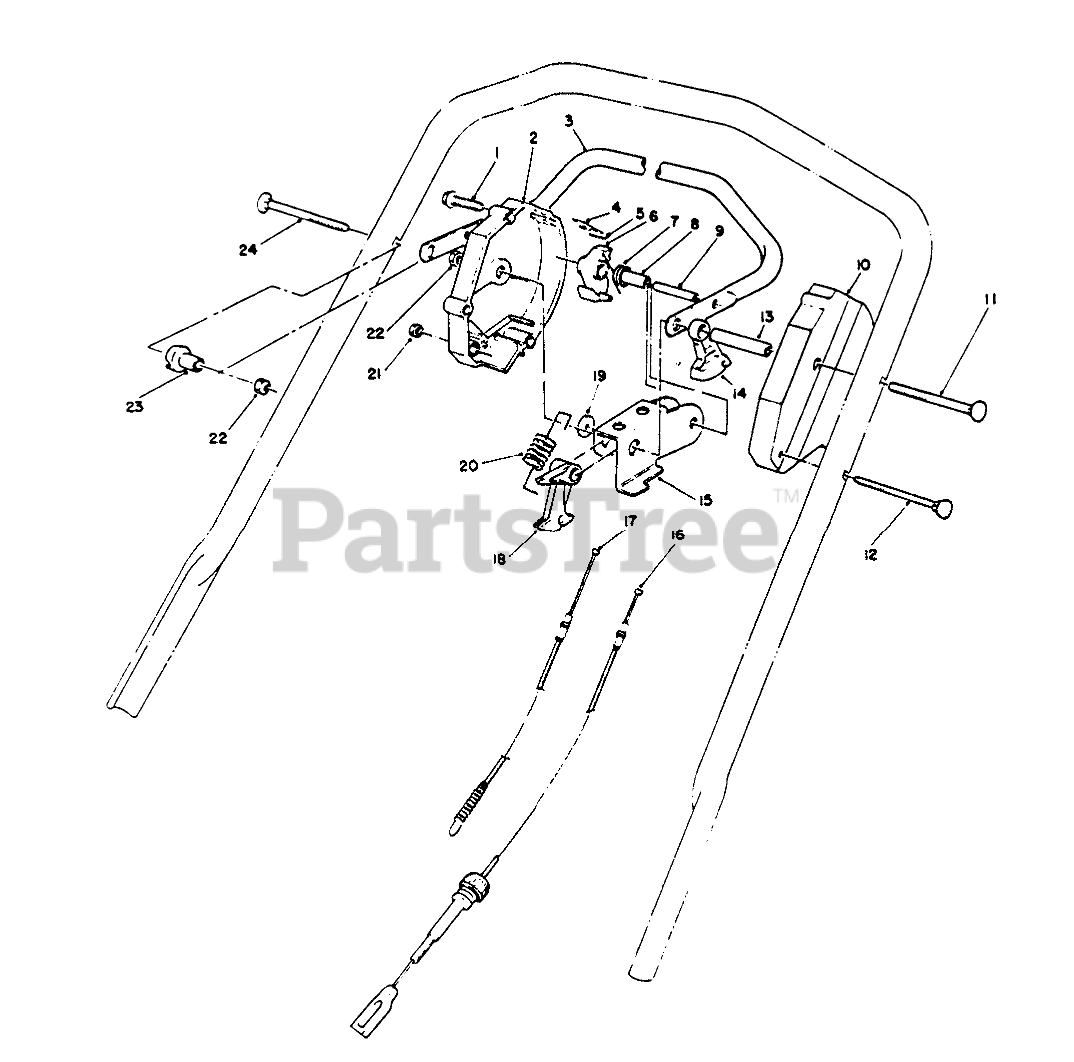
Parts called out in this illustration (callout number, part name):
1	SCREW-HWHTF
2	Housing-Control R.H. (Incl Ref. #4 & 5)
3	Bar-Control
4	SPRING-LEAF
5	PIN-INSERT
6	HOOK-CONTROL
7	SPRING-TORSION
8	SPACER
9	PIN-ROLL, SLOTTED
10	HOUSING-CONTROL, LH
11	5/16-18 X 3 HNDLE SCREW
12	HANDLE SCREW
13	TUBING-SPACER
14	LEVER-TRACTION
15	ROCKER
16	TRACTION CABLE
17	Cable-Clutch
18	LEVER-CABLE
19	WASHER-NYLON
20	SPRING-DETENT
21	NUT-HEX
22	NUT-LOCK, NI
23	SPACER-SUPPORT
24	5/16-18 X 2 HNDLE SCREW
